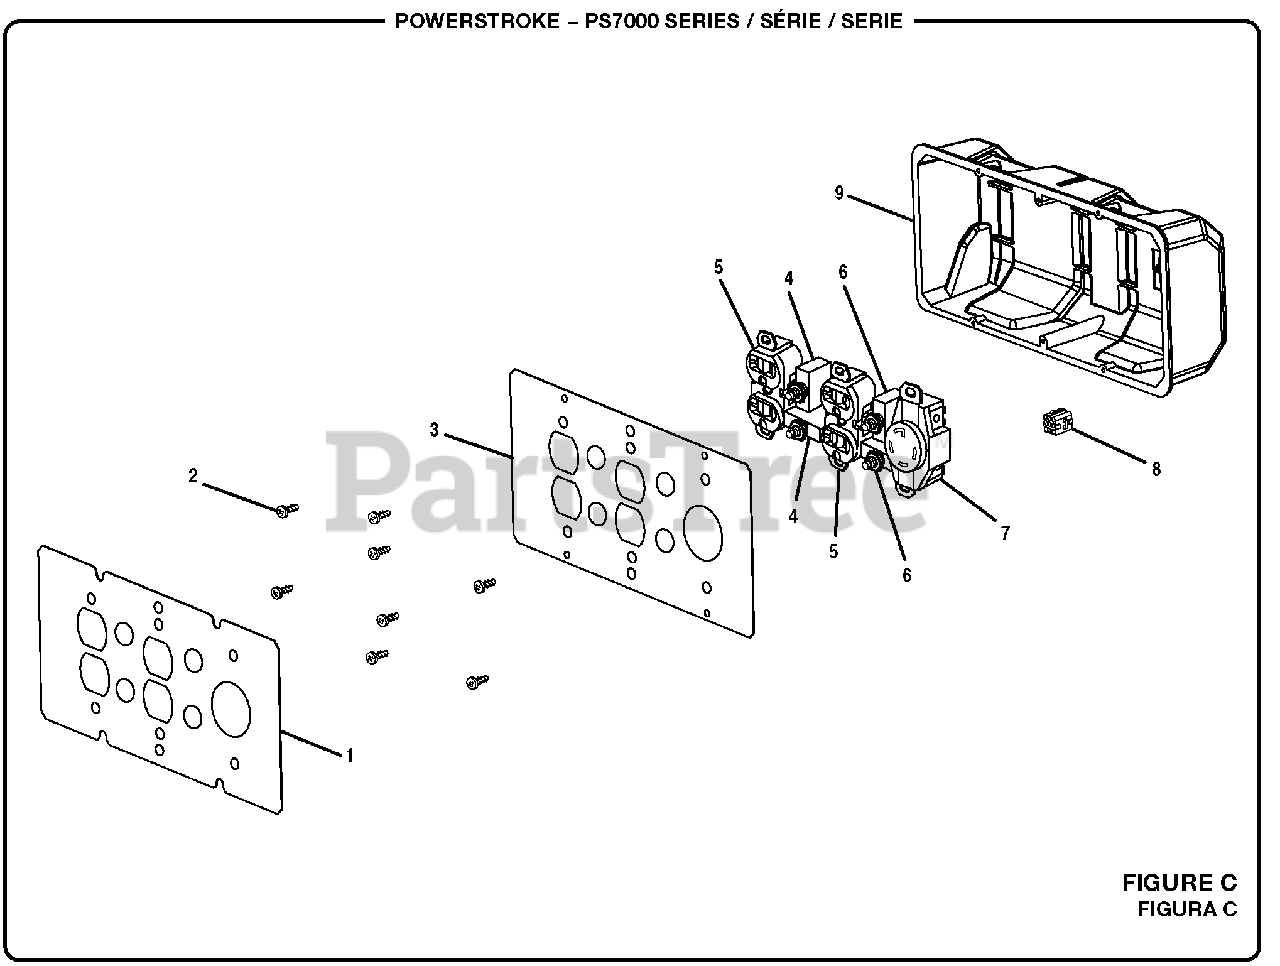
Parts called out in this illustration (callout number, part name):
1	Label (Power Outlet)
2	Screw (6-20 x 3/8 in.)
3	Front Panel
4	Circuit Breaker (20 Amp, 125 Volt)
5	120 Volt Duplex Receptacle
6	Circuit Breaker (30 Amp)
7	Twist Lock Receptacle (120/240 Volt, 30 Amp, L14-30R)
8	Connector (9 Pin)
9	Control Box (Back Panel)
